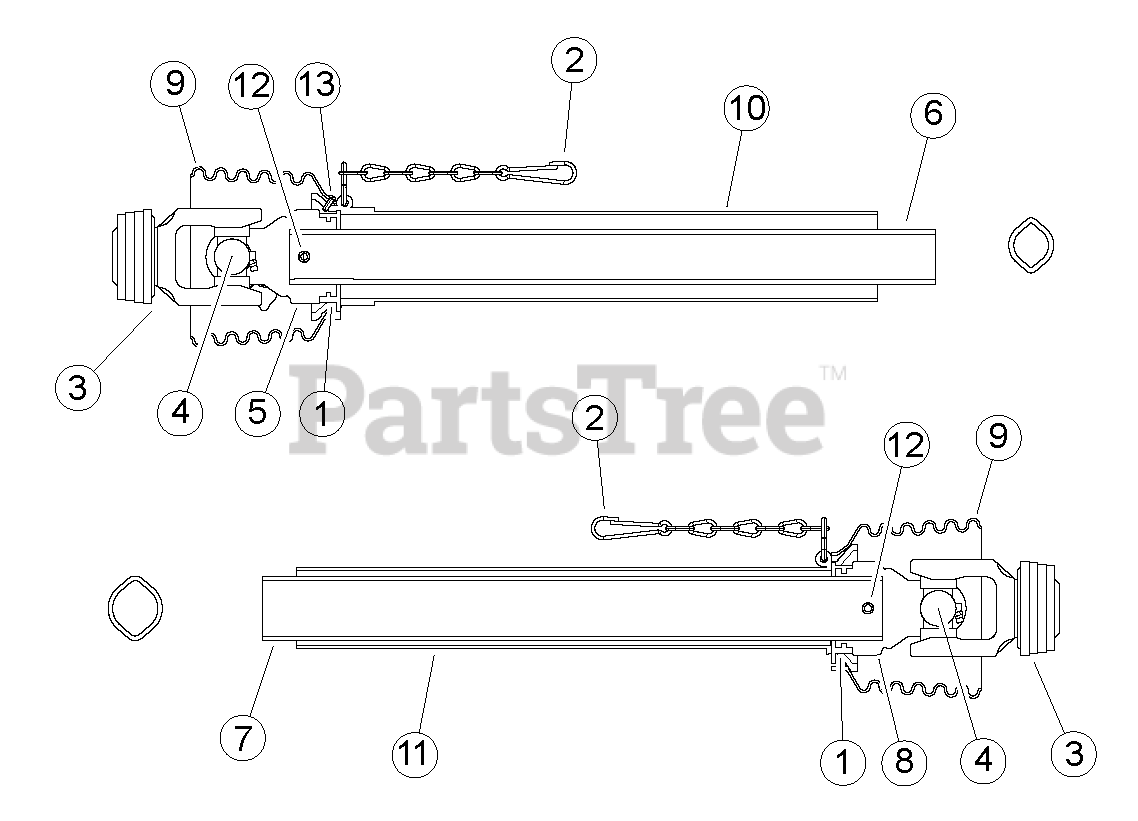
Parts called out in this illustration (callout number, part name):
1	RING, SC15 BEARING
2	CHAIN, SAFETY
3	YOKE, 1-3/8-6 SPLINGE ASGE
4	KIT, CROSS & BEARING
5	YOKE, INBOARD 0V
6	PROFILE, INNER 0V
7	PROFILE, OUTER 1
8	YOKE, INBOARD 1
9	CONE, 4 RIB
10	GUARD, TUBE OUTER
11	GUARD, TUBE INNER
12	PIN, 10 X 65 SPRING
13	SCREW, WS365344
